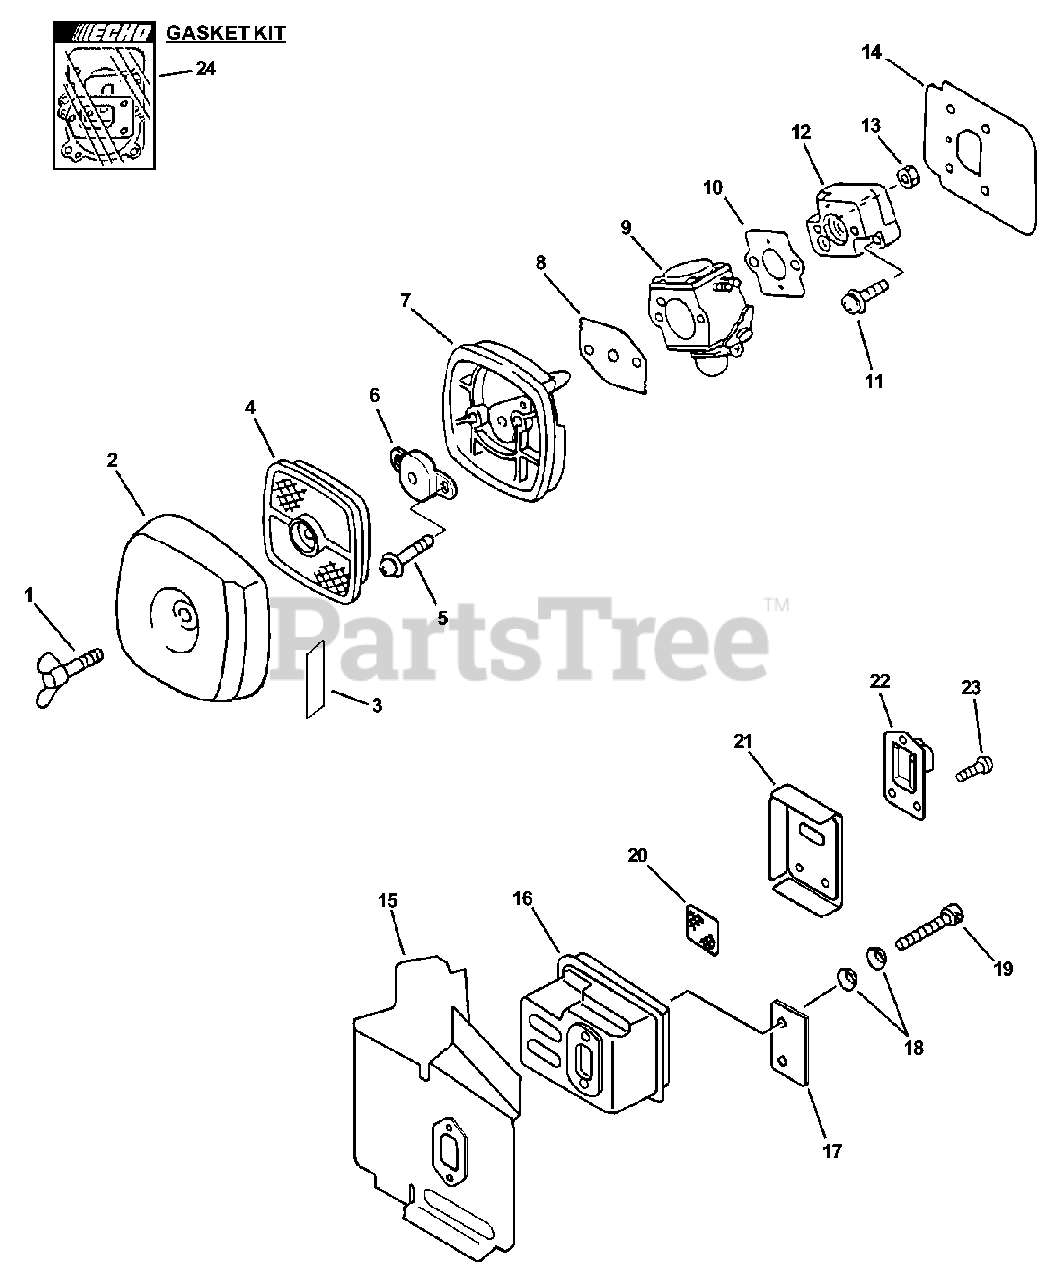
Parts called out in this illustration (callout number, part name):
1	THUMBSCREW
2	COVER, AIR FILTER - GRAY
3	LABEL - CHOKE
4	FILTER, AIR - SINGLE LAYER
5	SCREW - 5X65
6	PLATE, PREVENT
7	CASE, AIR FILTER - GRAY
8	GASKET, INTAKE
9	CARBURETOR C1U-K58
10	GASKET, INTAKE
11	SCREW - 5X20
12	INSULATOR, INTAKE
14	SHIELD, INTAKE
15	SHIELD, EXHAUST
16	MUFFLER
18	WASHER - CONICAL
19	SCREW - 5X55
20	SCREEN, SPARK ARRESTOR
21	GASKET, EXHAUST
22	GUIDE, EXHAUST
23	SCREW - 4X12
24	GASKET KIT
